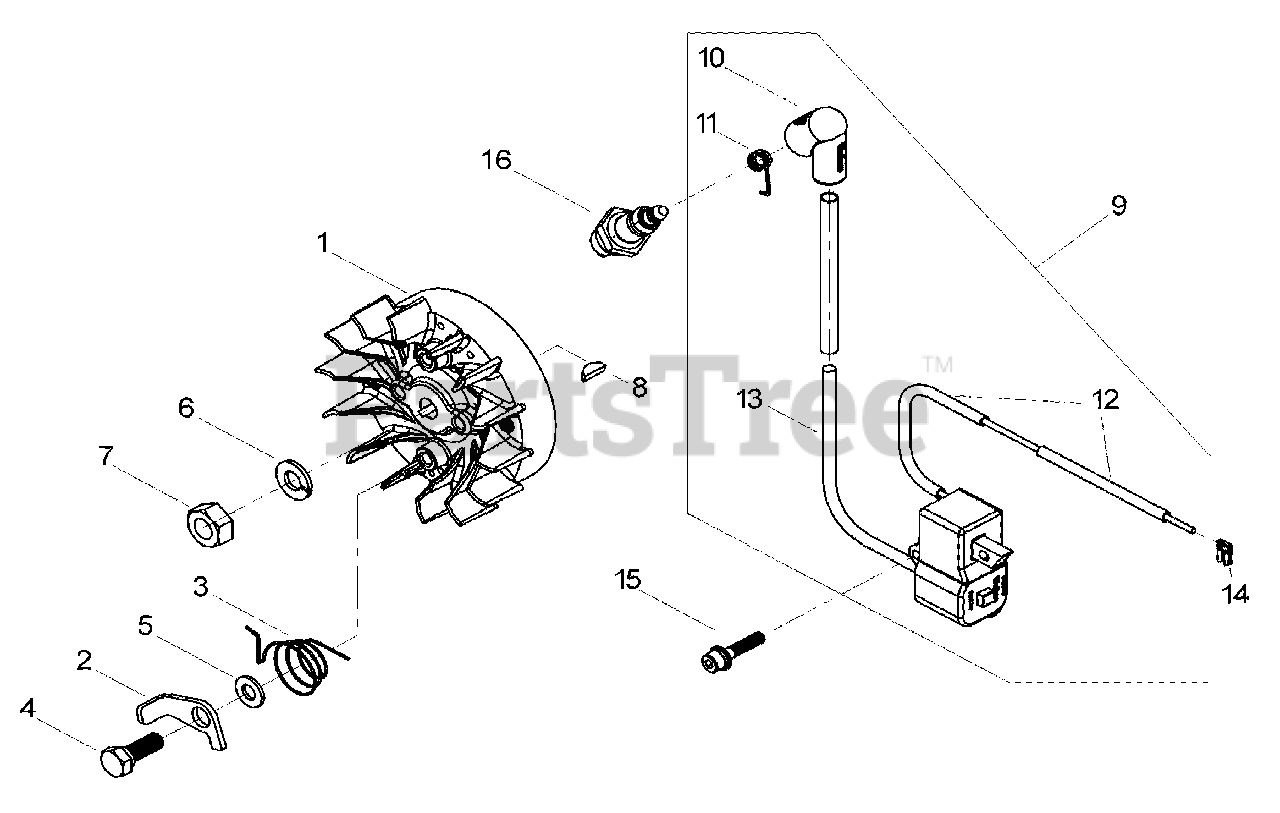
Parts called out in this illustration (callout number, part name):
1	FLYWHEEL
2	PAWL
3	SPRING, TORSION
4	BOLT 6
5	WASHER 6
6	WASHER, SPRING 8
7	NUT
8	KEY, WOODRUFF 3×10
9	COIL ASSY
10	CAP, SPARK PLUG
11	SPRING, COIL
12	PIPE
14	CONNECTOR
15	BOLT M4×20
16	SPARK PLUG - BPMR7A
